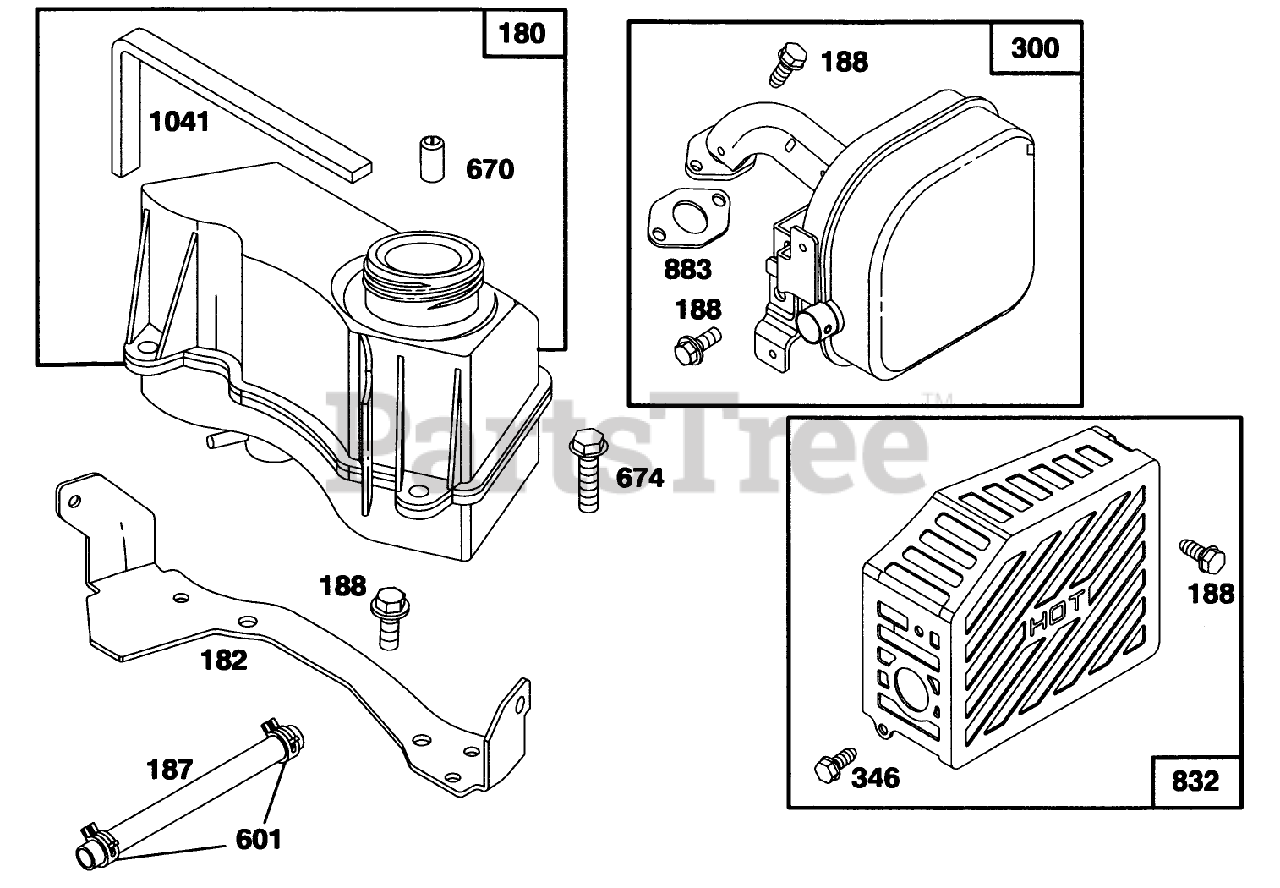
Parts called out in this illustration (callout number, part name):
180	TANK ASSY - FUEL
300	MUFFLER - EXHAUST
670	SPACER
674	SCREW - HEX HEAD
